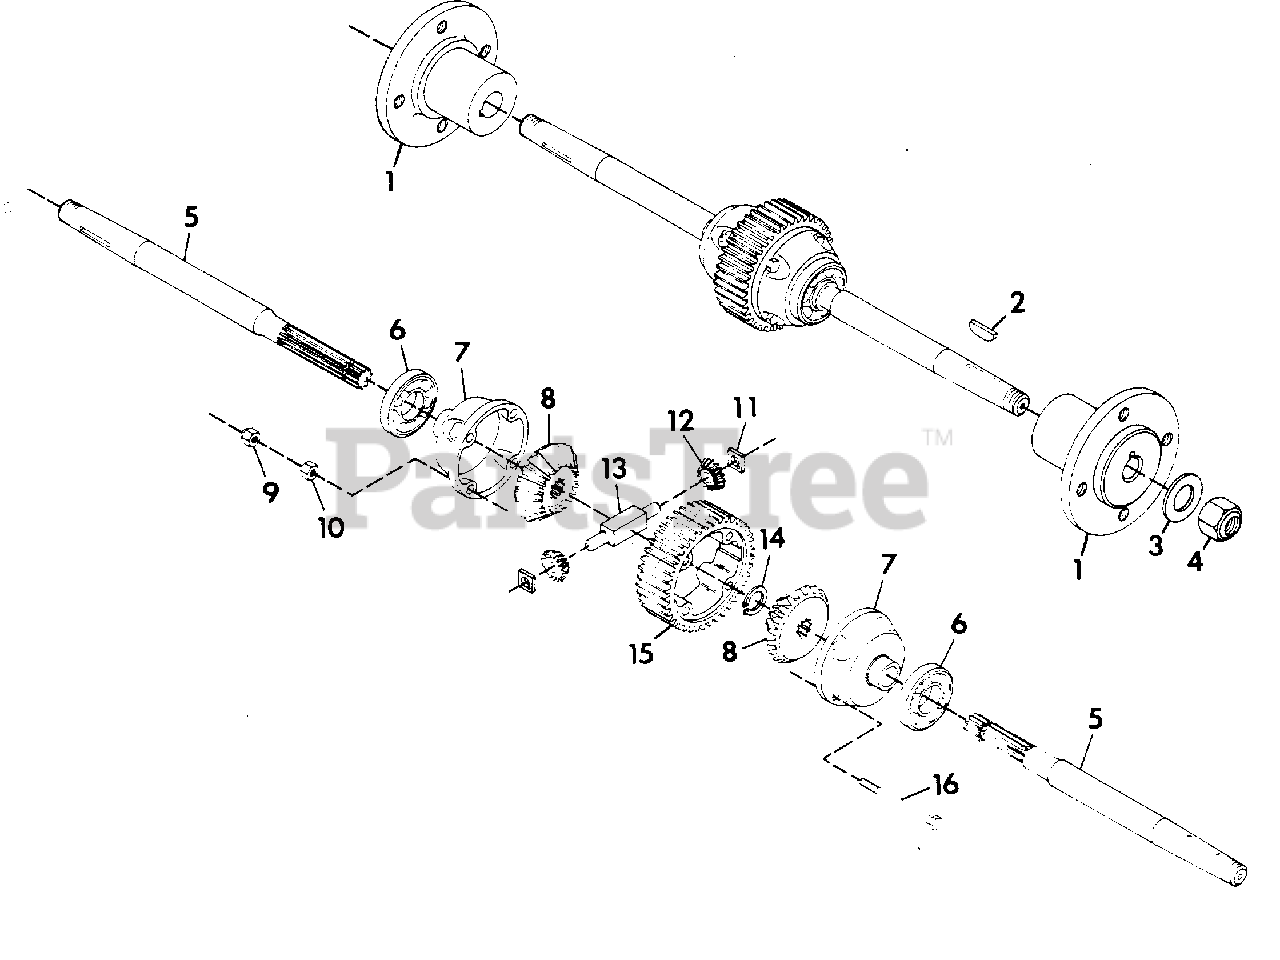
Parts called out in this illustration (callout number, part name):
1	HUB, OFC 60"
2	KEY, WOODRUFF .250X2.125 SOFT
3	WASHER, FLAT .813X2.0X.148
4	NUT, LOCK 3/4-10
5	AXLE
6	BEARING, BALL 1.378X2.834X.669
7	CAP, DIFFERENTIAL END
8	GEAR, BEVEL
9	NUT, LOCK 5/16-18
10	NUT, HEX 5/16-18 GR. 8
11	BLOCK, DRIVE
12	PINION, BEVEL
13	PIN, SPIDER PINION
14	RING, RETAINING
15	GEAR, FINAL DRIVE
16	BOLT, HEX 5/16-18X2.75 GR. 8
